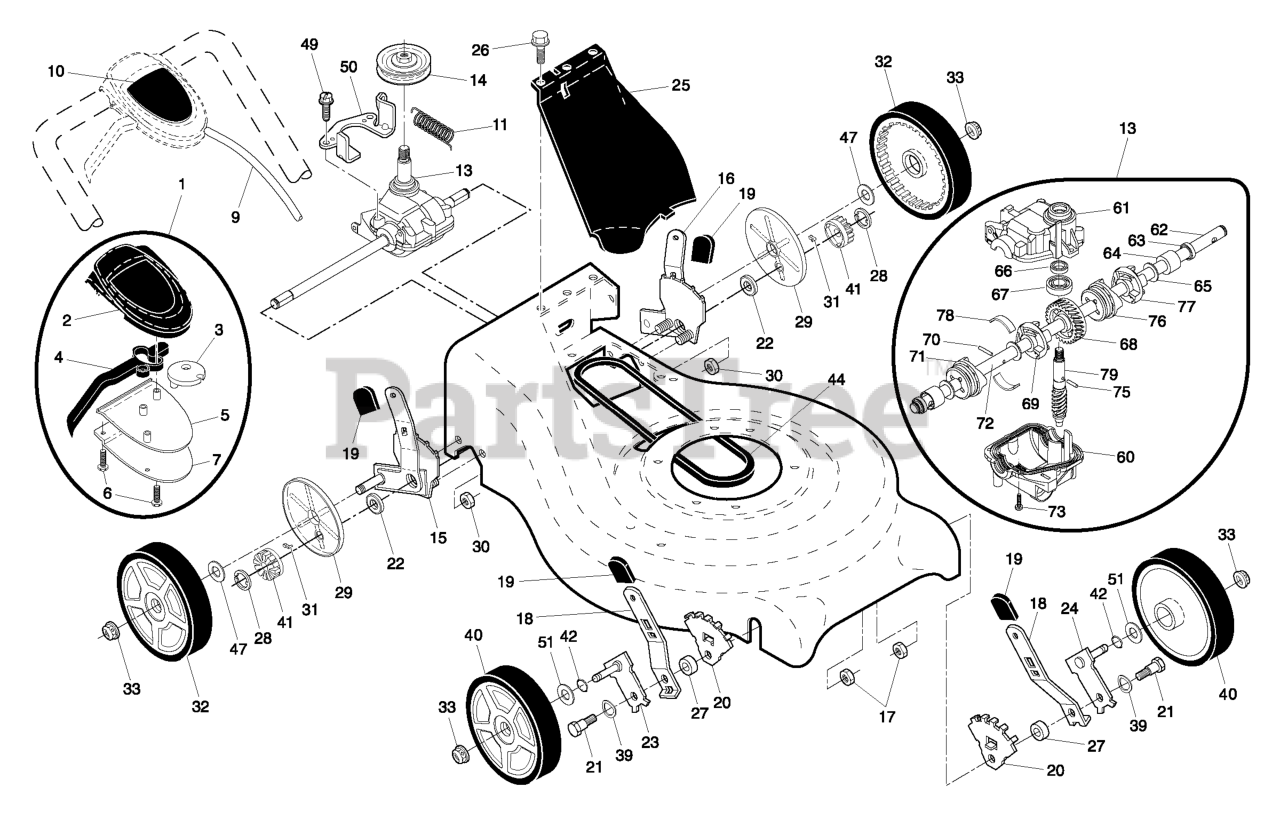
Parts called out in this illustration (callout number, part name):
1	DRIVE CONTROL ASSY, AUTO WALK
2	COVER.TOP.DRIVE.CONTROL.BLACK
3	PULLEY.CAM.DRIVE.CONTROL.EZ
4	LEVER, AUTOWALK DRIVE CONTROL
5	COVER.BOTTOM.DRIVE.CNTRL.BLACK
6	SCREW, PHILLIPS HEAD 10 X 5/8
7	BRACKET.DRIVE.CONTROL.MOUNT.BL
9	CABLE.ASSY.RGD.EZ.AUTO
10	DECAL, DRIVE
13	TRANSMISSION.21.RWGD
14	PULLEY.1.PIECE
15	KIT.ADJUSTER.ASM
16	KIT WHEEL ADJ LH
17	LOCKNUT 5/16-18
18	SELECTOR SPRING, FRONT
19	KNOB.DELUXE.GRAY
20	WHEEL ADJ BRACKET FRONT
21	SHOULDER BOLT 5/16-18
22	BEARING
23	AXLE ARM ASSY FRONT RH
24	AXLE ARM ASSY FRONT LH
25	COVER.DRIVE.21.RWGD.MO
27	SPACER.HEIGHT.ADJUSTER
28	E-RING 7/16 RE
29	COVER.DUST.WHEEL
30	LOCKNUT.NYLOC.1/4-20
31	PAWL, DRIVE
32	WHEEL.8X1.75.
33	NUT.HEX.FLANGE.3/8-16.LO(3 2)
34	PINIION.14.TOOTH.RGD
39	WASHER.CURVED.CYLINDRICAL
40	FRONT WHEEL AND TIRE ASSY 8X2
42	O-RING..070X.487.NEOPRENE
44	BELT.RGD.VS
47	WASHER FLUT
50	BELT KEEPER
51	WASHER.FLAT.1/2
60	CASE, LOWER
61	CASE UPPER
62	Long Shaft
63	SEAL.OUTPUT.SHAFT
66	SEAL INPUT SHAFT
68	GEAR 28 TEETH
69	DOG.FIXED.LH.32003
70	PIN 7 33732
71	DOG.MOVEABLE.LH.32005
72	Short Shaft
75	PIN 3.50.337 - 33733
76	DOG.FIXED.RH.32004
77	DOG.MOVEABLE.RH.32006
78	SPRING LEAF
79	SHAFT WORM
